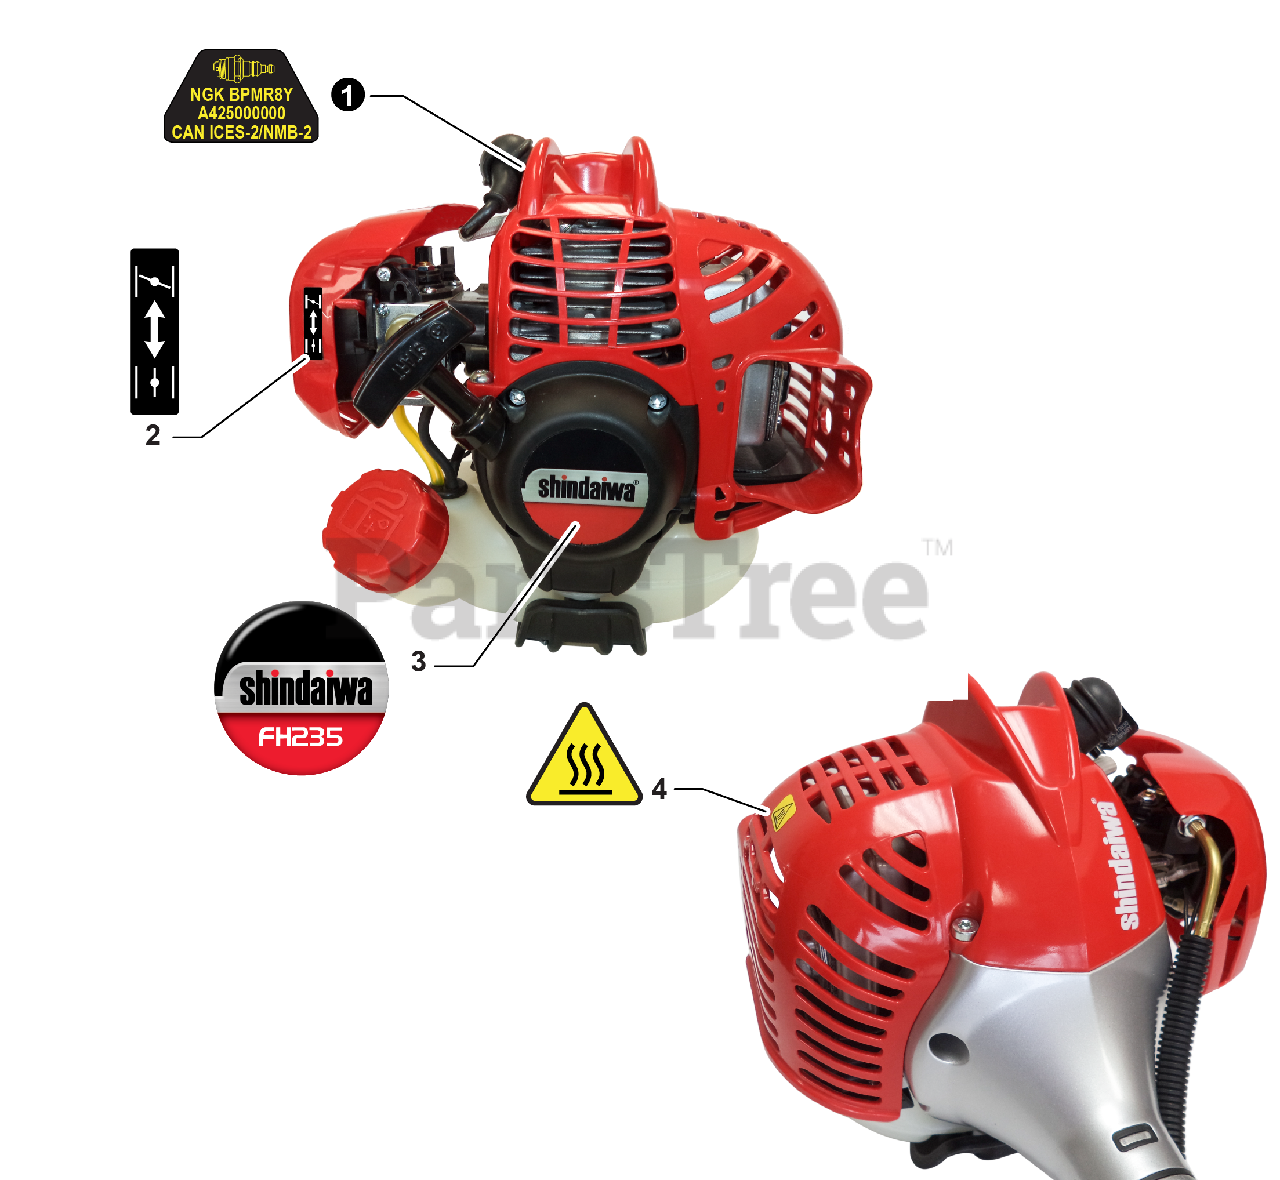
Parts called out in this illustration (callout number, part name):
1	LABEL, SPARK PLUG - BPMR8Y
2	LABEL, CHOKE
3	LABEL, SHINDAIWA - FH235
4	LABEL, CAUTION - HOT
